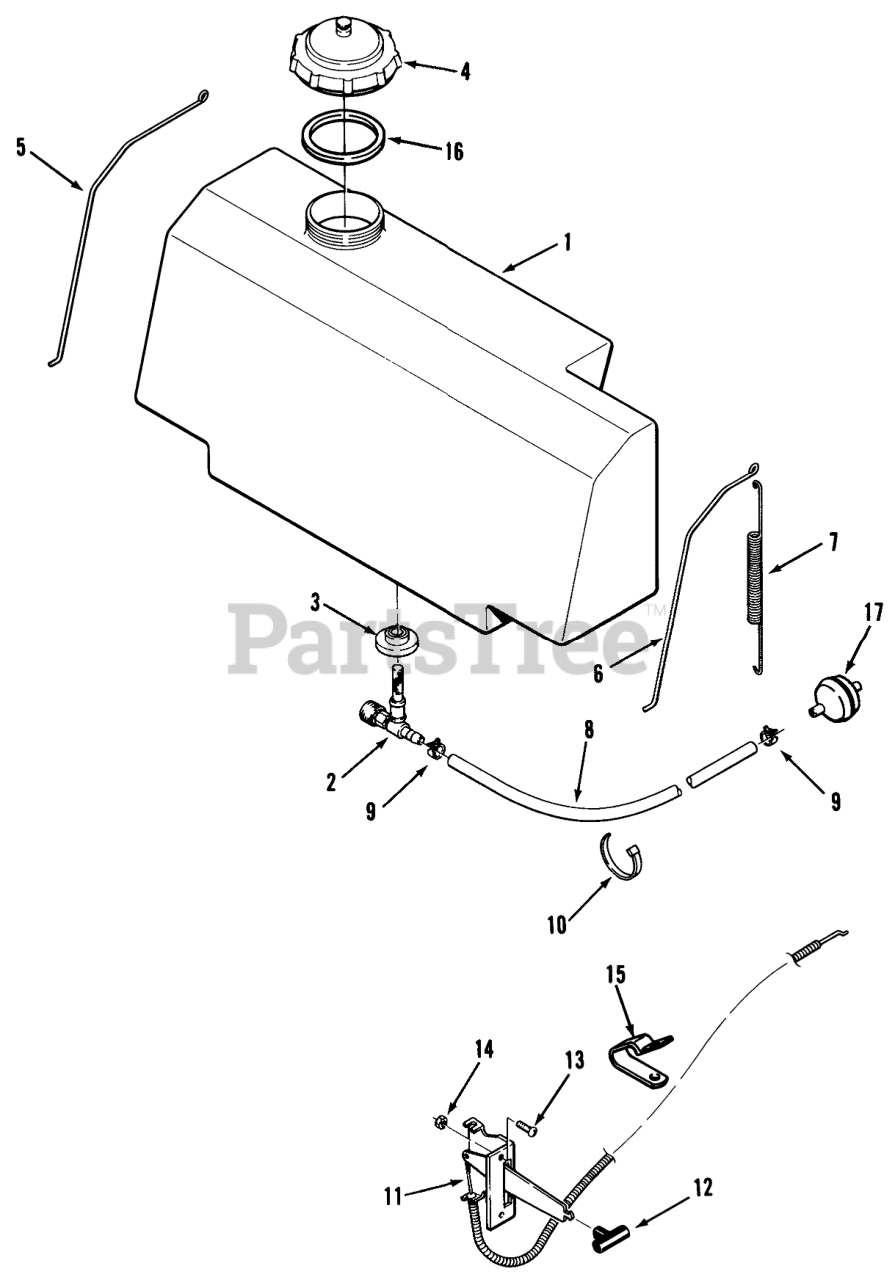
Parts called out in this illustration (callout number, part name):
1	Fuel Tank (includes items 2 & 3)
2	VALVE-FUEL
3	BUSHING
4	ASSY FUEL CAP
5	RETAINER TANK RH
6	RETAINER TANK LH
7	SPRING EXTENSION
8	Fuel Hose 8.5"(22cm)
9	Clamp
10	PLASTIC TIE
11	Pedal-Clutch
12	KNOB-CONTROL
13	Screw
14	Nut
15	CLAMP DOUBLE
16	GASKET-GAS CAP
17	FILTER-FUEL
